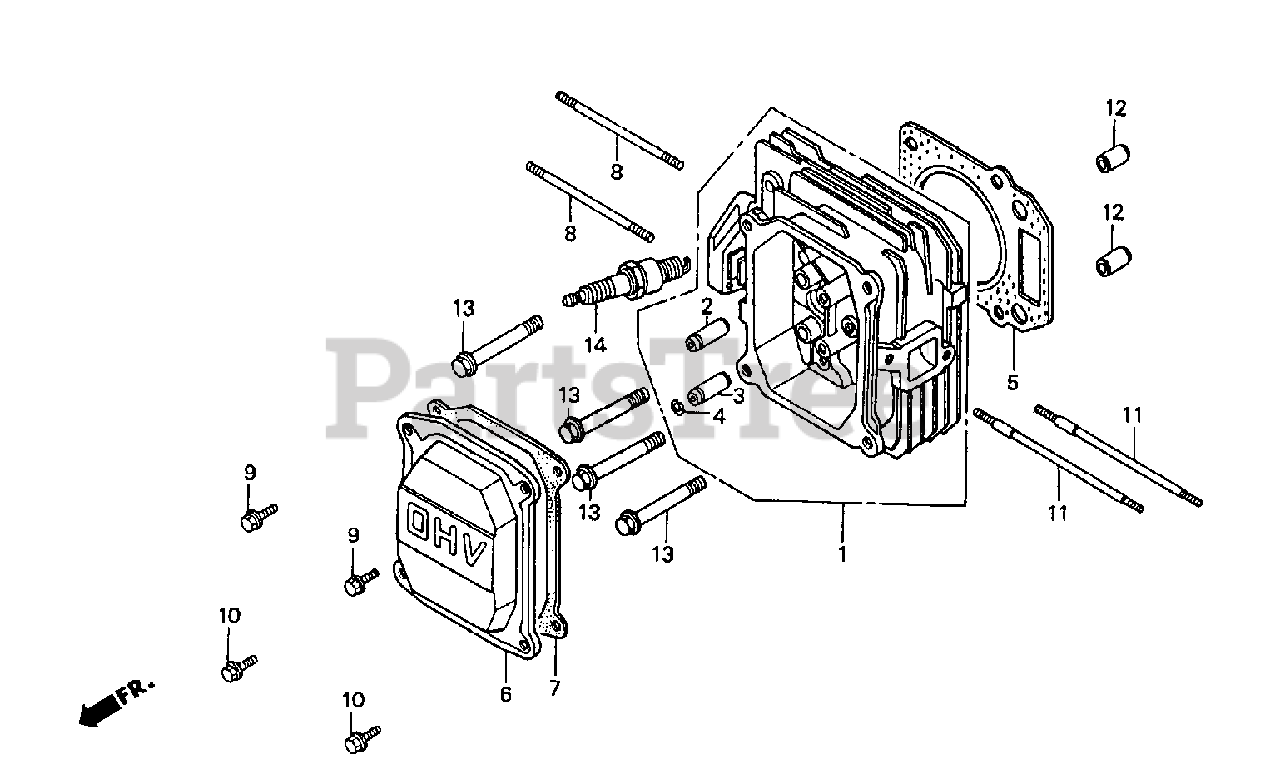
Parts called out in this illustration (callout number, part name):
1	CYLINDER HEAD
2	GUIDE, VALVE (OVER SIZE) Use up to Engine SN 2416541.
2	GUIDE, VALVE (OVER SIZE) Use from Engine SN 6324986.
3	GUIDE, EX. VALVE (OS)
4	CLIP, VALVE GUIDE Use from Engine SN 1231803.
5	GASKET, CYLINDER HEAD
6	COVER, HEAD
7	GASKET, CYLINDER HEAD COVER
8	BOLT, STUD (6X82)
9	BOLT, FLANGE (6X14)
10	BOLT, FLANGE (6X13)
11	BOLT, STUD (6X109)
12	PIN A, DOWEL (10X16)
13	BOLT, FLANGE (8X50)
14	SPARK PLUG (BPR4ES) (NGK)
14	SPARK PLUG (W14EPR-U) (DENSO)
14	SPARK PLUG (BP5ES) (NGK)
14	SPARK PLUG (BPR5ES) (NGK)
14	SPARK PLUG (W16EP-U) (DENSO)
14	SPARK PLUG (BP6ES) (NGK)
14	SPARK PLUG (BPR6ES) (NGK)
14	SPARK PLUG (W20EP-U) (DENSO)
14	SPARK PLUG (W20EPR-U) (DENSO)
